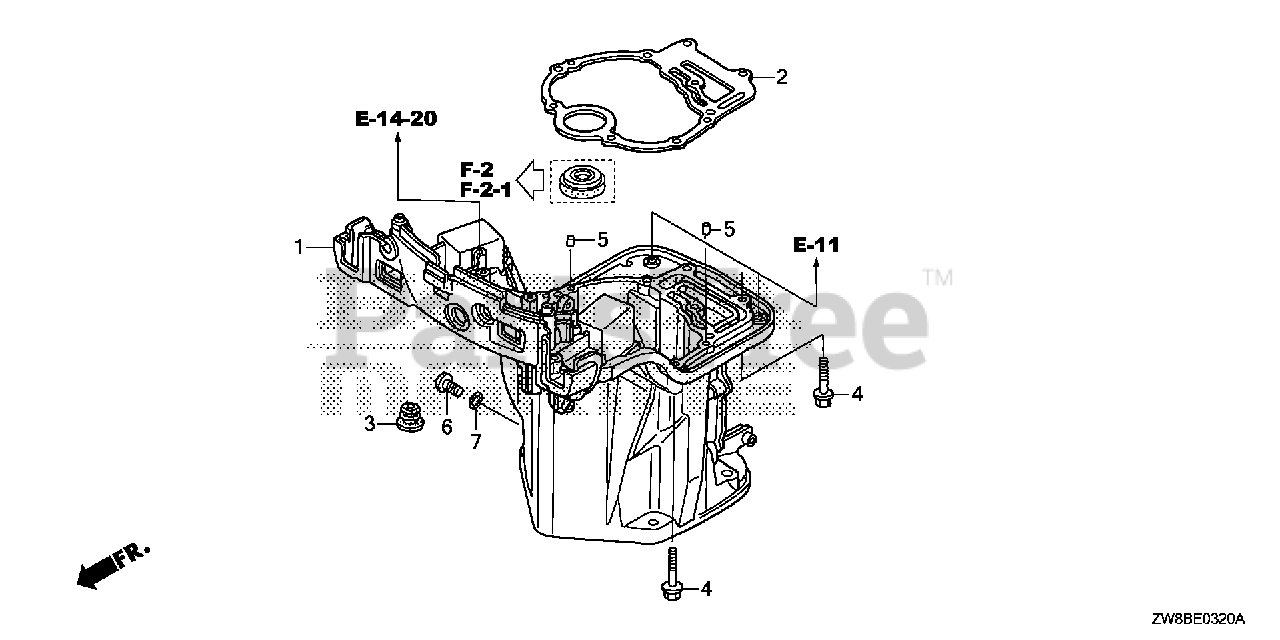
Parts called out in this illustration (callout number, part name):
1	CASE, OIL *NH282MU* (OYSTER SILVER METALLIC-U)
2	GASKET, OIL PAN
3	GROMMET, WATER TUBE
4	BOLT, FLANGE (8X35) Use from Frame SN 4800713.
5	PIN A, DOWEL (6X10)
6	BOLT, OIL CHECK
7	O-RING (5.5X1.5)
